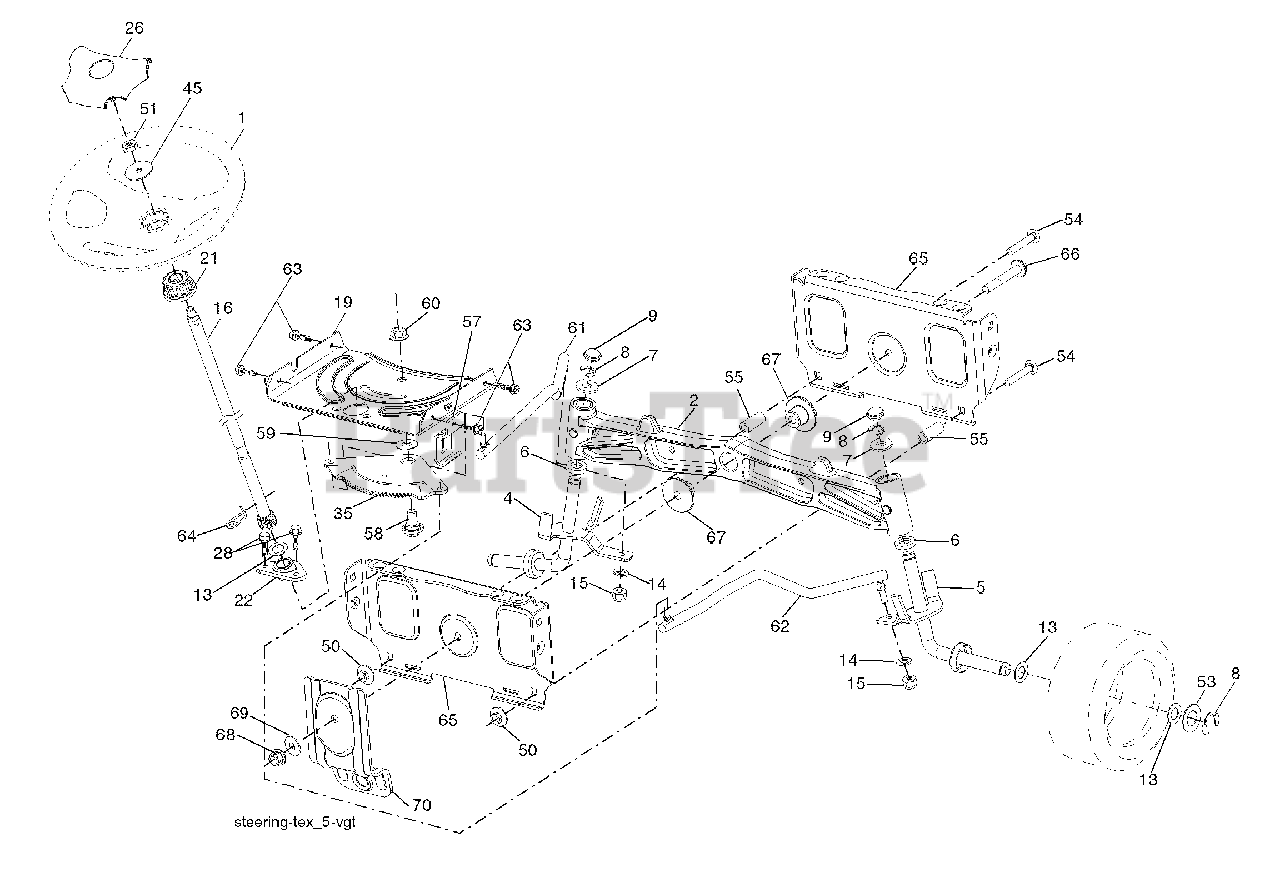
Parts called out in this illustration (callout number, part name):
1	Wheel, Steering
2	Axle Asm., Front
4	Spindle Asm., LH
5	Spindle Asm., RH
6	Bearing, Race Thrust Harden
7	Washer 25/32 x 1-5/8 x 16 Ga.
8	Ring, Klip #T5304-75
9	Cap, Spindle
13	Washer 25/32 x 1-1/4 x 16 Ga.
14	Washer, Lock Hvy Hlcl Spr 3/8
15	Nut, Crown Lock 3/8-24 unf
16	Shaft Steering
19	Plate Steering
21	Adapter, Wheel Steering
22	Bushing, Strg. Blk
26	Insert, Wheel Steering
28	Screw 3/8-16 x 3/4
35	Gear, Sector Plate
45	Washer 9/16 ID x 2-3/8 OD 12 Ga.
50	Nut Lock 3/8-16 unc
51	Nut Hex Jam Toplock 1/2-20 unf
53	Washer Hardened .793 x 1.637 x .060
54	Bolt Hex 3/8-16 unc x 2-1/4
55	Spacer Brace Axle
57	Bracket Upstop
58	Bolt Shoulder Sector Pivot CFM
59	Washer Thrust Sector Steering
60	Nut Flange Lock 5/8-11
61	Draglink LH
62	Draglink, RH
63	Screw 5/16-18 x 3/4
64	Retainer Clip Spring Steering
65	Brace Axle Front
66	Bolt Hex Fghd 7/16-14 x 3 Serr
67	Bushing PM Front Axle
68	Nut Lock Flange 7/16-14 Gr. 5
69	Washer 1.5 x .505 x .118
70	Bracket Deck Susp. Front
